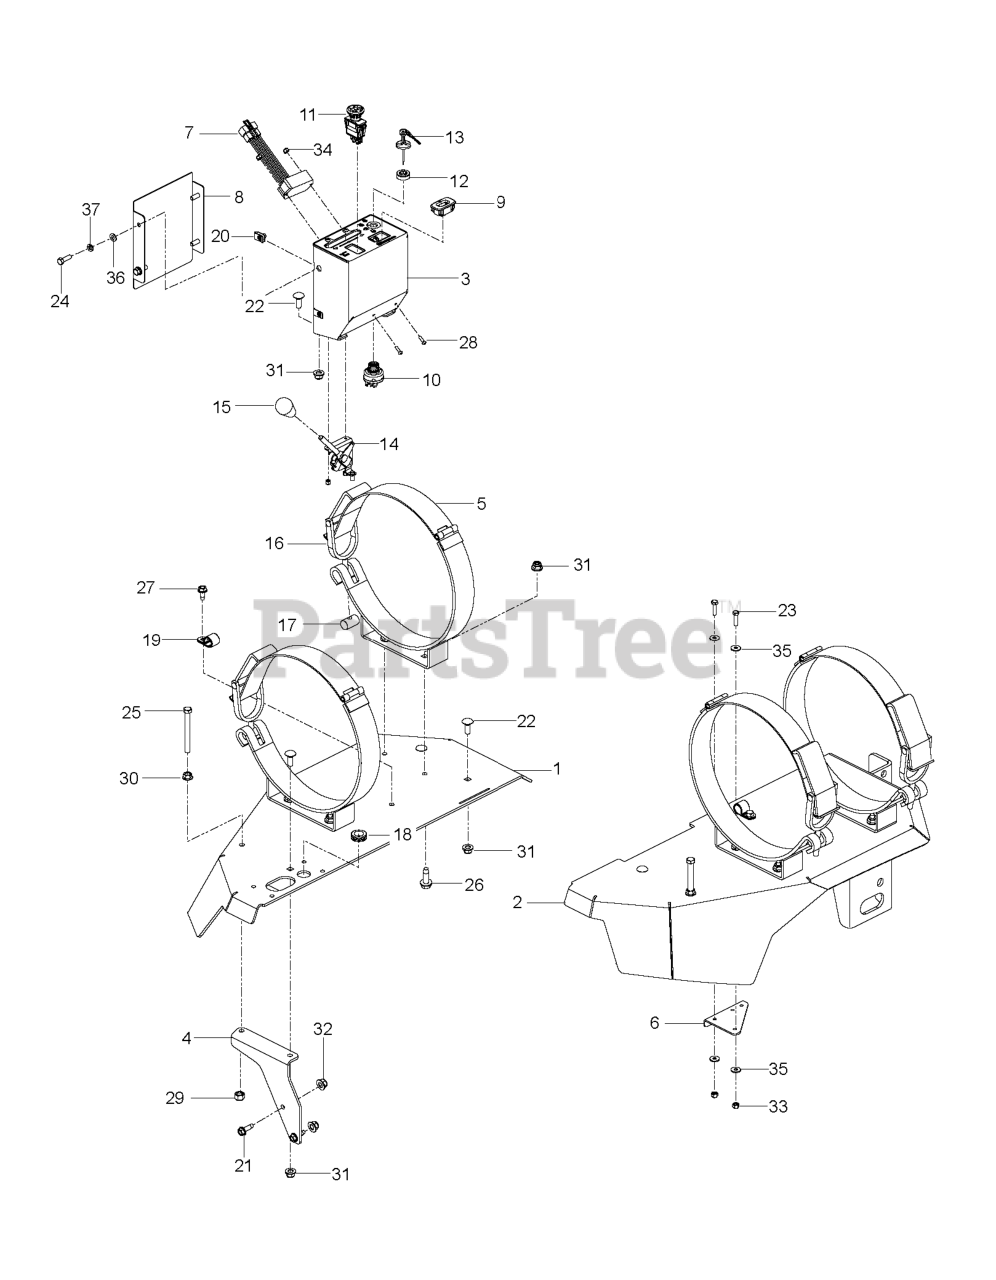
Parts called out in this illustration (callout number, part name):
2	Bushings
3	Seals
9	Gaskets
11	Tubes
16	Crankshafts
24	Woodruff Key
26	Rings
32	Screws
250	Retainers
252	Collections
306	Shields
307	Screws
447	Screws
505	Nuts
562	Screws
